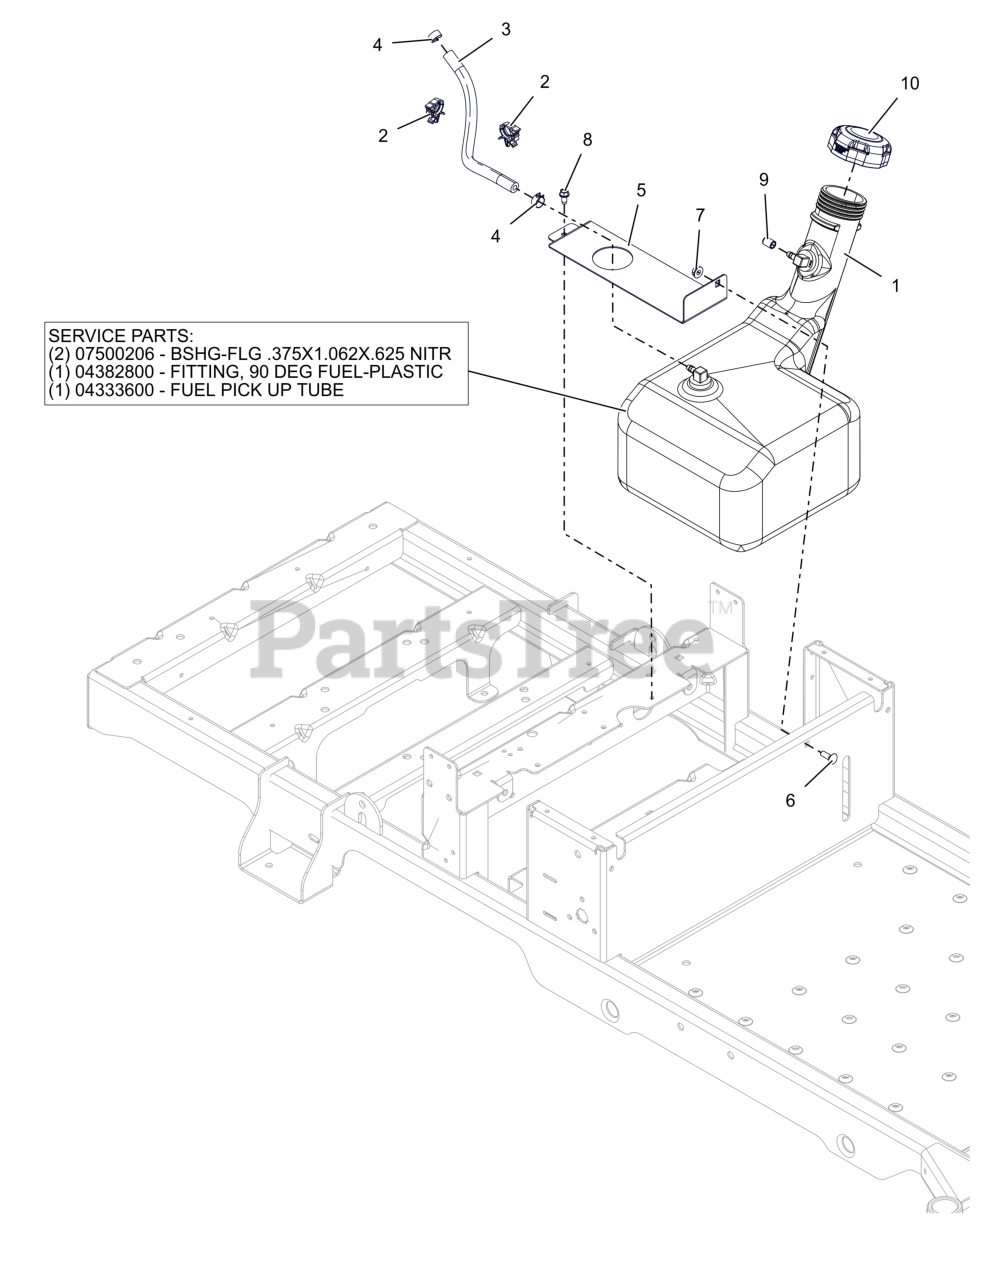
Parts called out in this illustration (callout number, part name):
1	ASM, FUEL TANK-ZOOM
1	BSHG-FLG .375X1.062X.625 NITR
1	FITTING, 90 DEG FUEL-PLASTIC
1	FUEL PICK UP TUBE
2	WIRE CLIP
3	HOSE, .25 LOW-PERM BULK GAS
4	CLAMP, FUEL LINE
5	BRKT, TANK STRAP
6	BLT, RHSN .25-20X.750 G5 ZCC
7	NUT-LK-CTR-FLG .25-20 ZC120
8	SCR-TAP .25-20X.50 HWH ZCC
9	CAP- FUEL OUTLET PORT
10	CAP, FUEL - 2.25 RATCHET INLET VENT
